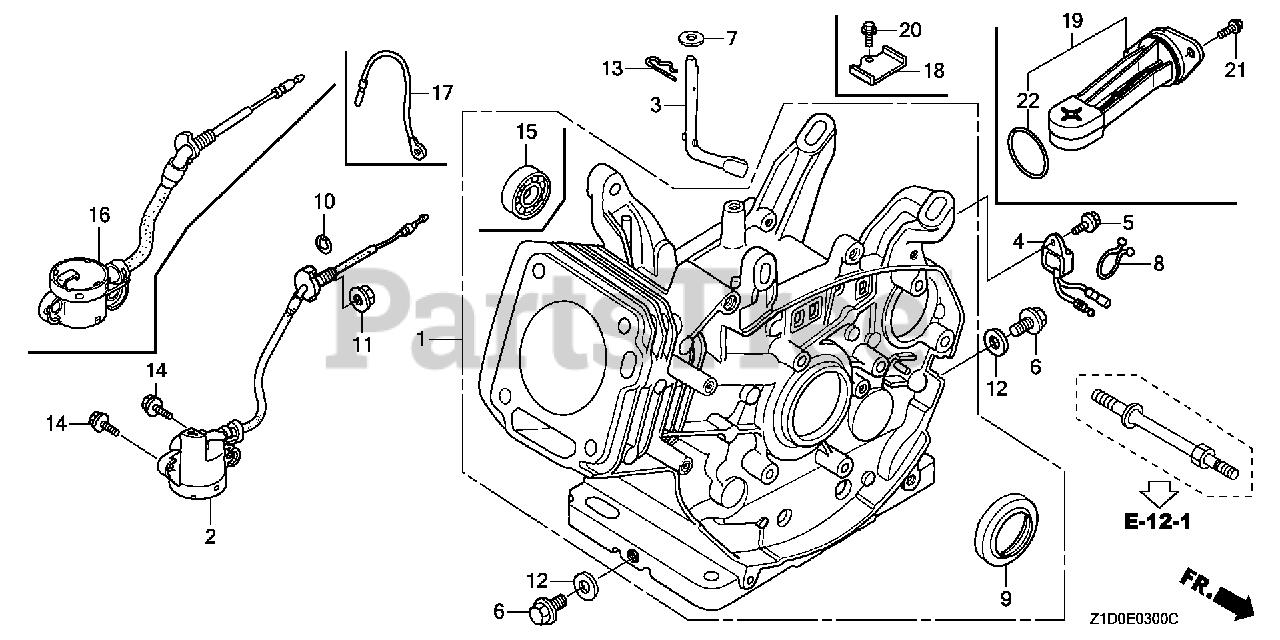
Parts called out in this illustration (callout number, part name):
1	CYLINDER ASSY.
3	SHAFT, GOVERNOR ARM
6	BOLT, DRAIN PLUG (12X15)
7	WASHER (8.2X17X0.8)
9	OIL SEAL (30X46X8) (NOK ASIA)
10	O-RING (13.5X1.5) (ARAI)
10	O-RING (14MM) (NOK)
11	NUT, FLANGE (10MM)
12	WASHER, DRAIN PLUG (12MM)
13	PIN, LOCK (10MM)
14	BOLT, FLANGE (6X12)
16	SWITCH ASSY., OIL LEVEL
